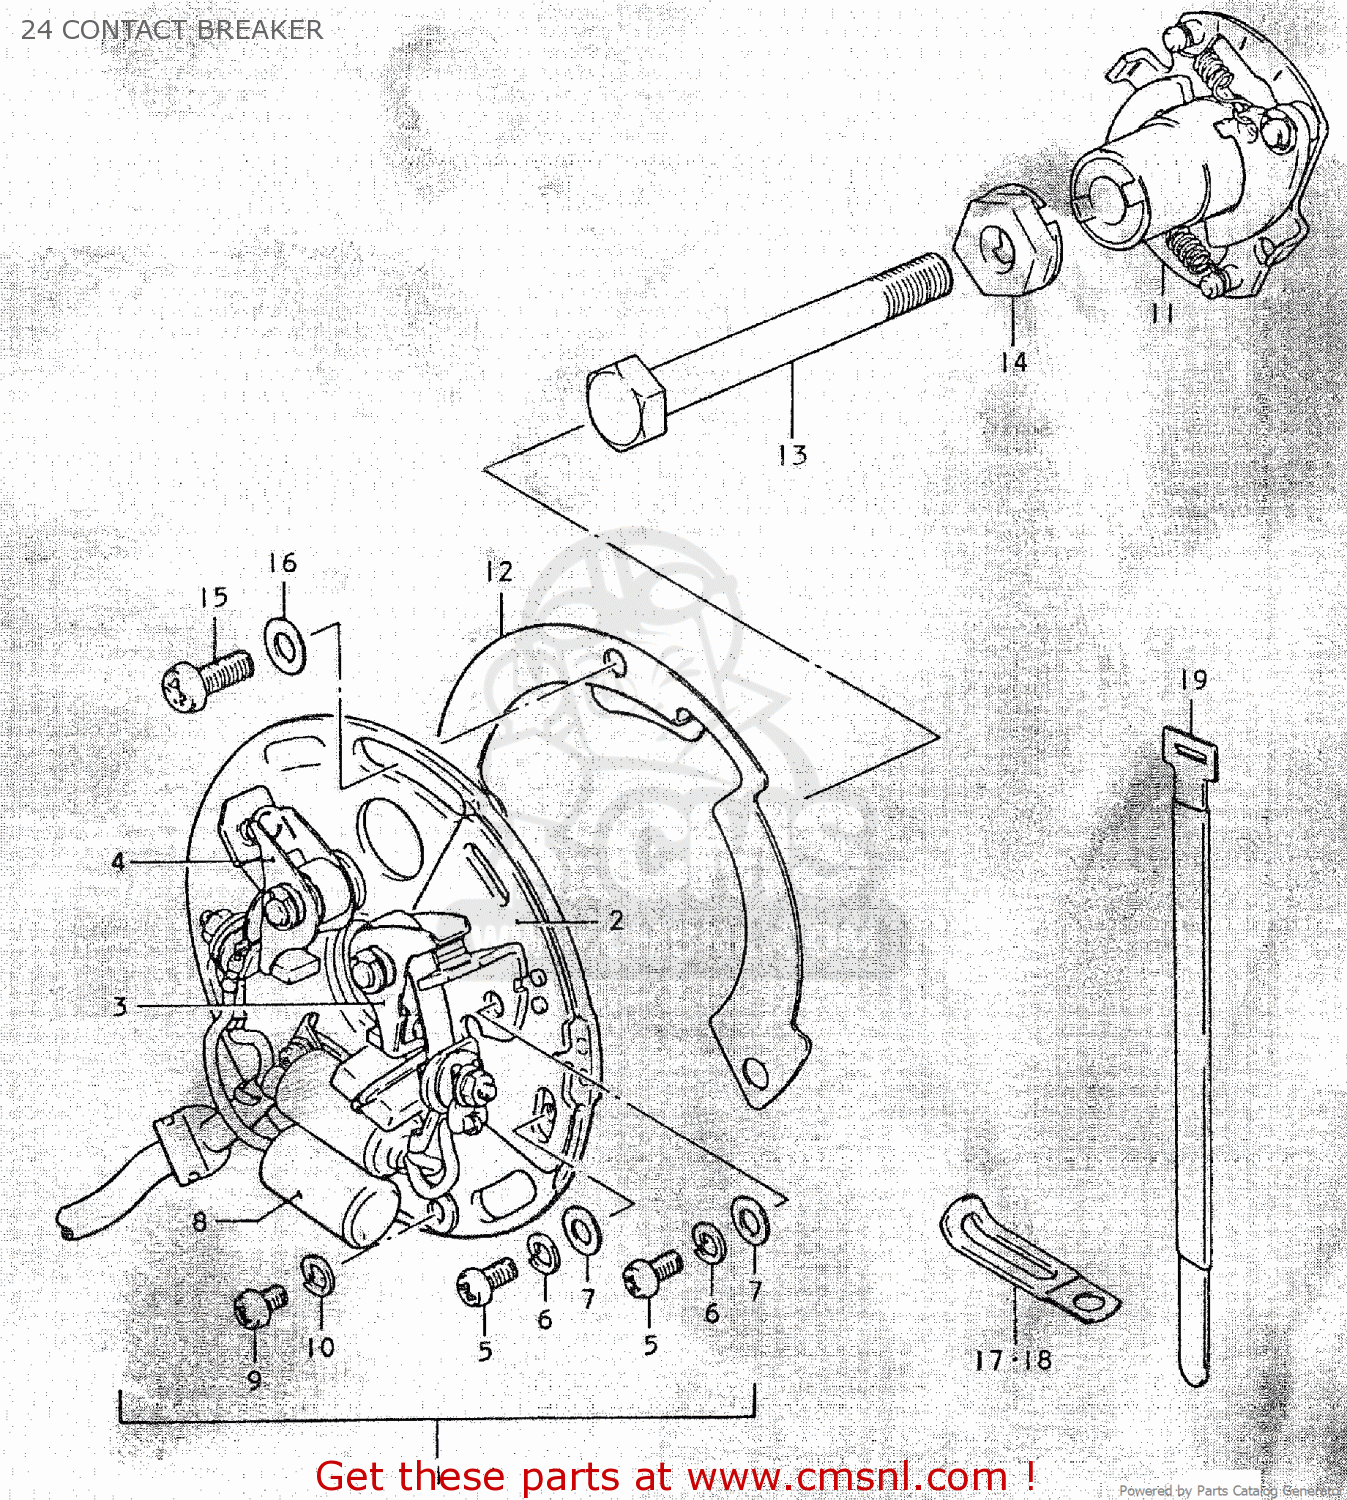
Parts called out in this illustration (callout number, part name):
1	BREAKER ASSEMBLY,CONTACT
2	PLATE,CONTACT POINT
3	POINT ASSY,R
4	POINT ASSY,L
5	SCREW(4X10)
6	LOCK WASHER
7	WASHER
8	CONDENSER
9	SCREW
10	LOCK WASHER
11	GOVERNOR ASSEMBLY
12	PLATE,IGNITION TIMING
13	BOLT
14	WASHER
15	SCREW(5X12)
16	WASHER 5MM
17	CLAMP L:35
18	CLAMP
19	CLAMP
